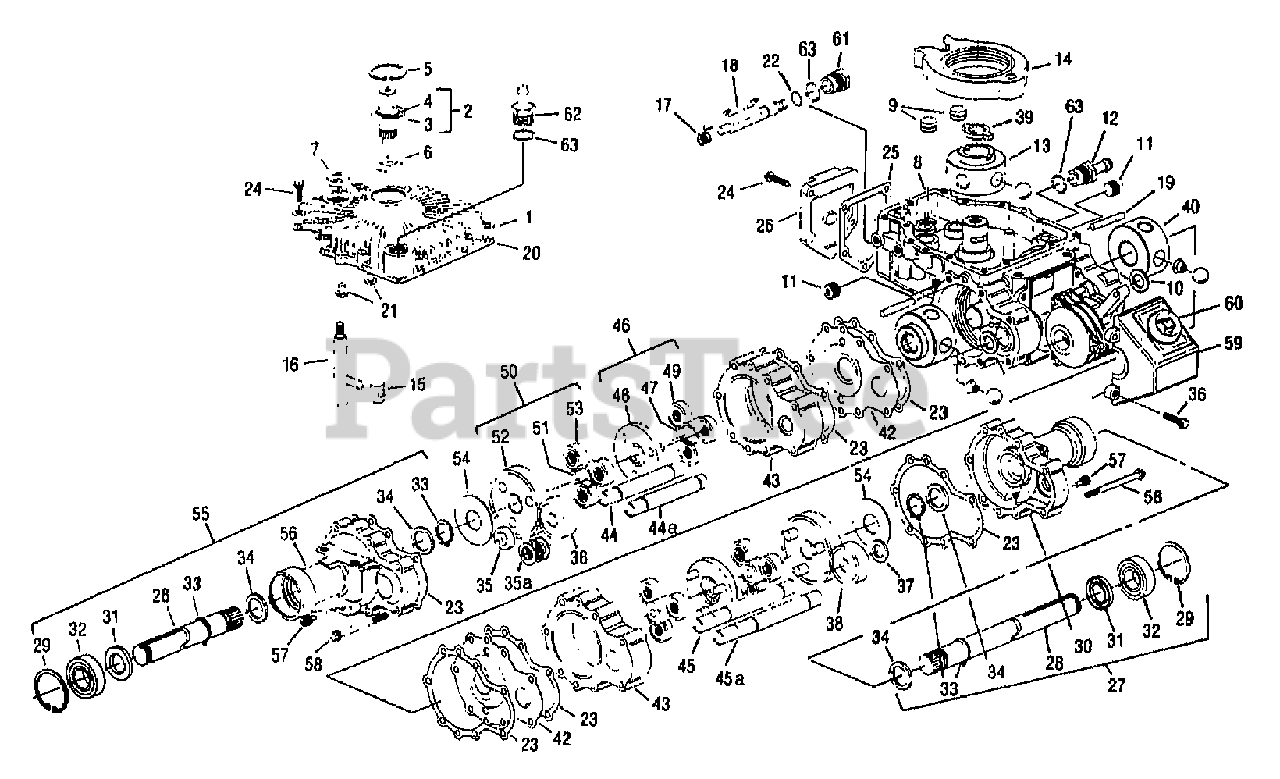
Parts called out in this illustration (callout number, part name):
5	RING-RETAINING INTERNAL
6	SEAL-INPUT SHAFT
7	SEAL-CONTROL SHAFT
17	SPRING-DUMP VALVE
18	BRACKET
22	RING-O
25	GASKET
63	RING-O
